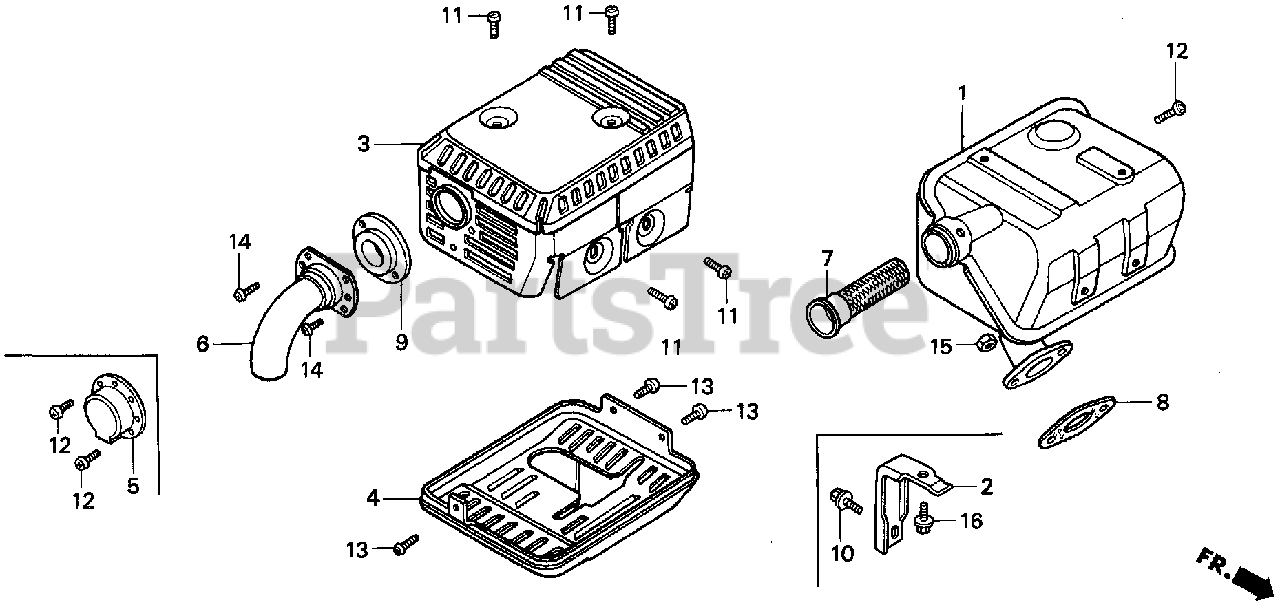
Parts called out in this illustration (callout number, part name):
1	MUFFLER
3	PROTECTOR, MUFFLER
7	ARRESTER, SPARK
8	GASKET, MUFFLER
11	SCREW, TAPPING (5X8)
12	SCREW, TAPPING (4X6)
15	NUT, HEX. (8MM)
